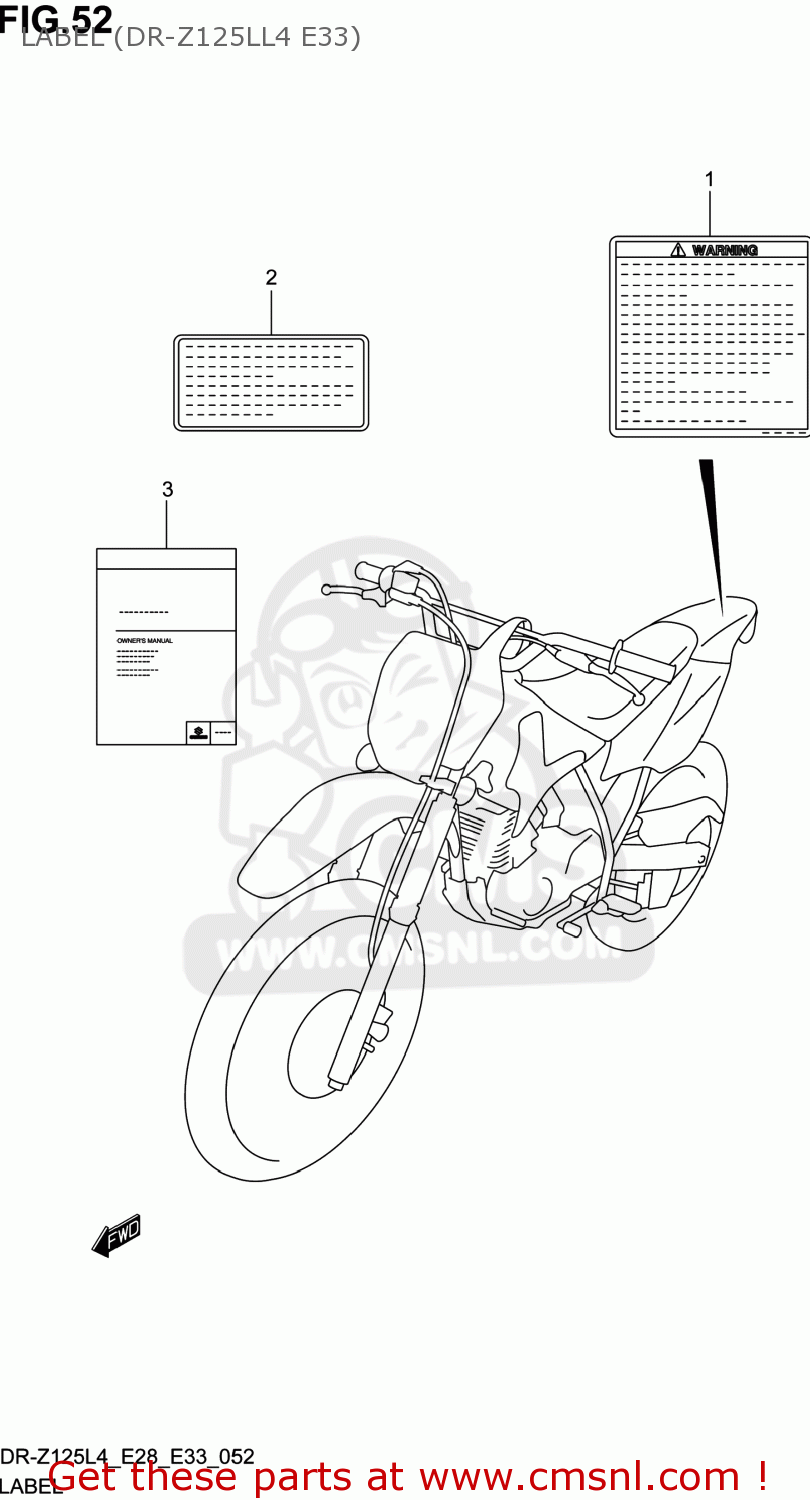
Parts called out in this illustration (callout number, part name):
1	LABEL,GENERAL WARNING
2	LABEL,MANUAL NOTICE
3	MANUAL,OWNER'S
